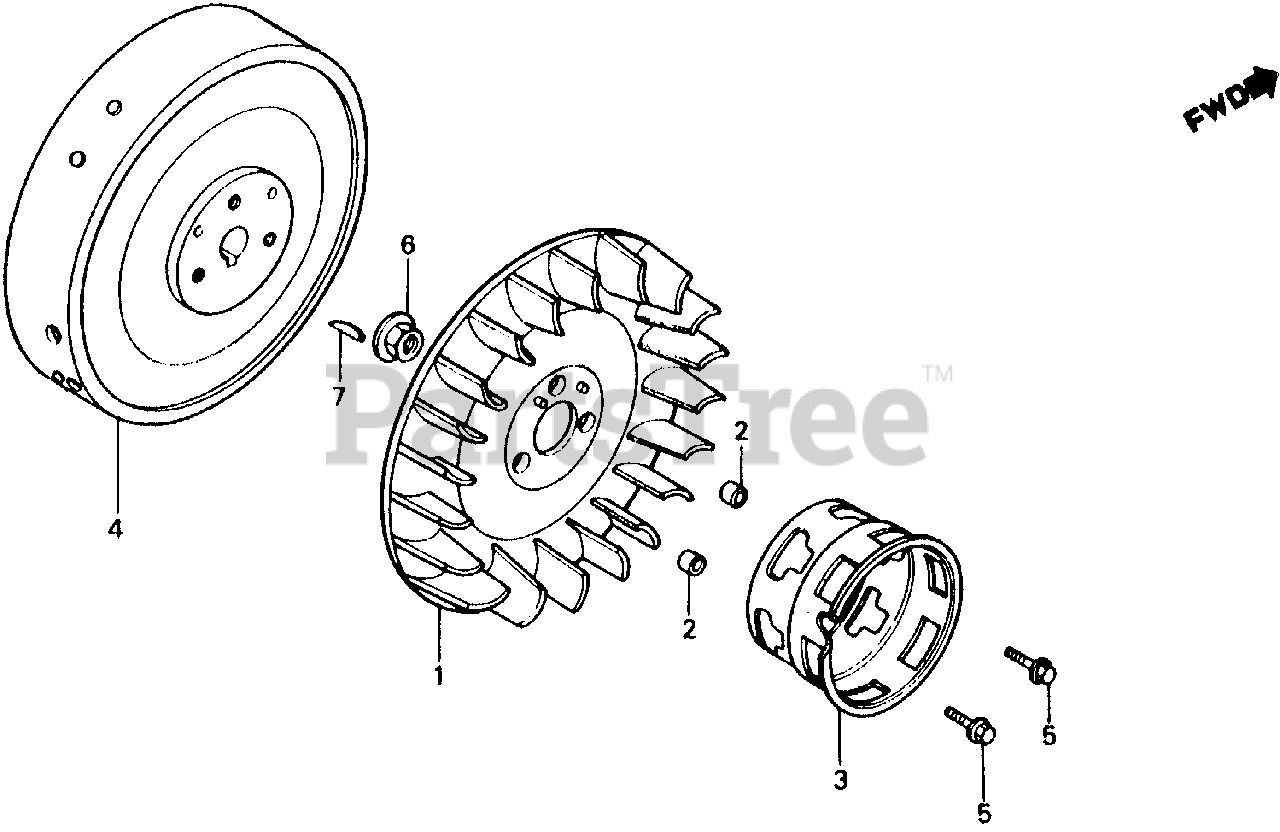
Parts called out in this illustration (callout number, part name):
1	FAN, COOLING
2	COLLAR, FAN
3	PULLEY, STARTER
4	FLYWHEEL (15W) (BREAKER+LAMP)
5	BOLT, FLANGE (6X16)
6	NUT, SPECIAL (16MM)
7	KEY, SPECIAL WOODRUFF (25X18)
